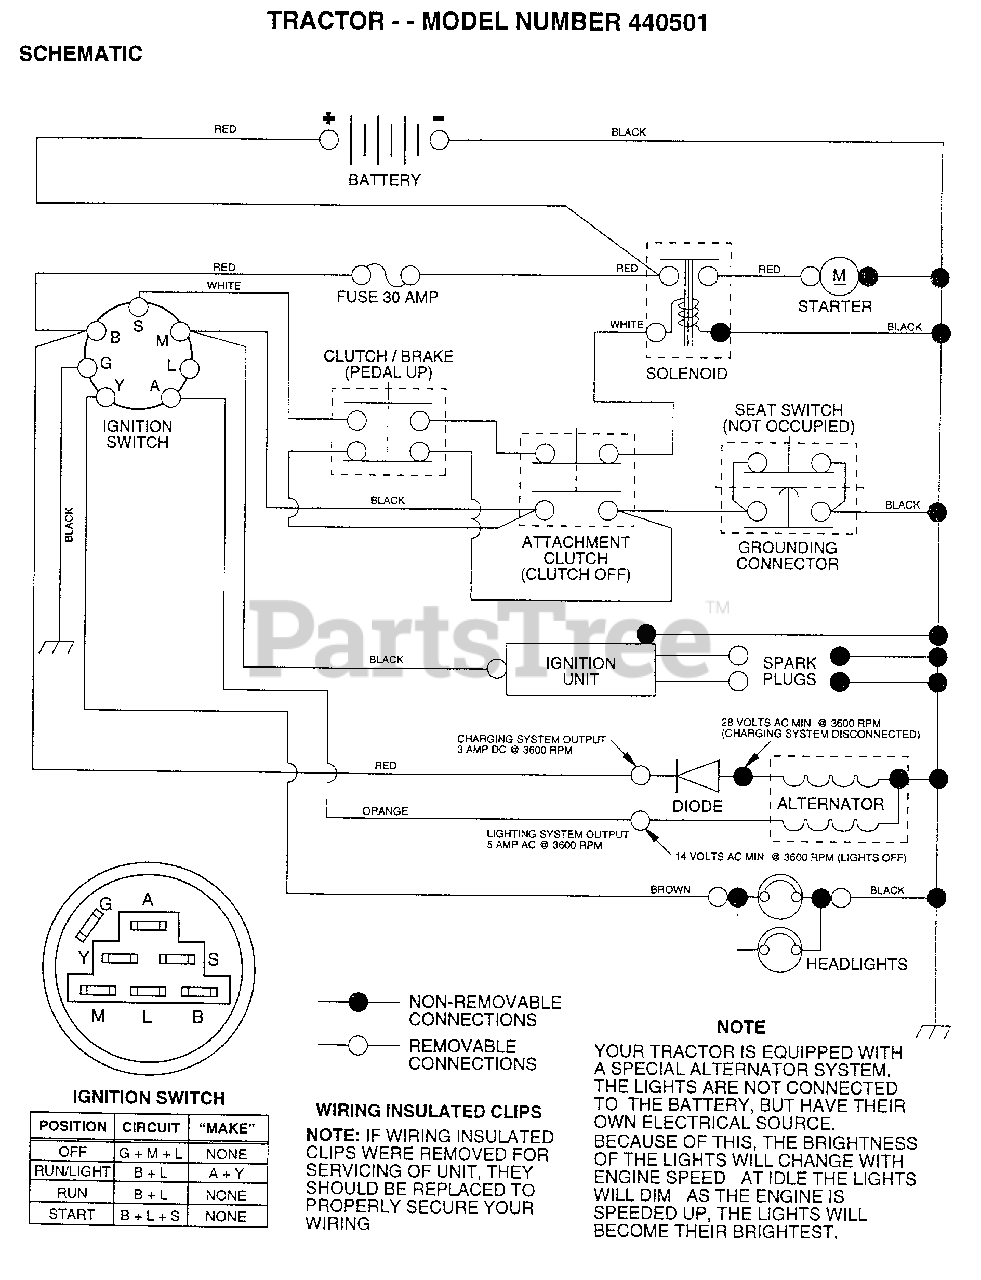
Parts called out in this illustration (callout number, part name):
2	BOLT LT
3	WASHER
4	LOCKWASHER
7	TUBE T
9	HOSE CLAMP T
15	FASTNER.SNAP-IN
16	SWITCH INTERLOCK
20	NUT
21	"HARNESS,LIGHT SOC"
22	HEADLAMP BULB
24	CABLE-BATTERY T
25	CABLE.BTRY.6GA.RD
26	FUSE HYT
28	CABLE T
29	SWITCH SEAT
30	SWITCH IGN 4POS
31	NUT IGNITION
32	COVER KEY SWITCH
33	KEY
36	SCREW
38	BRACKET SWITCH IN
39	SWITCH INTERLOCKT
40	HARNESS.IGNITION
41	BOLT HXHD FIN
44	NUT HXKEP 1/4X20
48	ADAPTER AMMETER
52	PROTECTION LOOP
70	HARNESS.ENG.LT.
